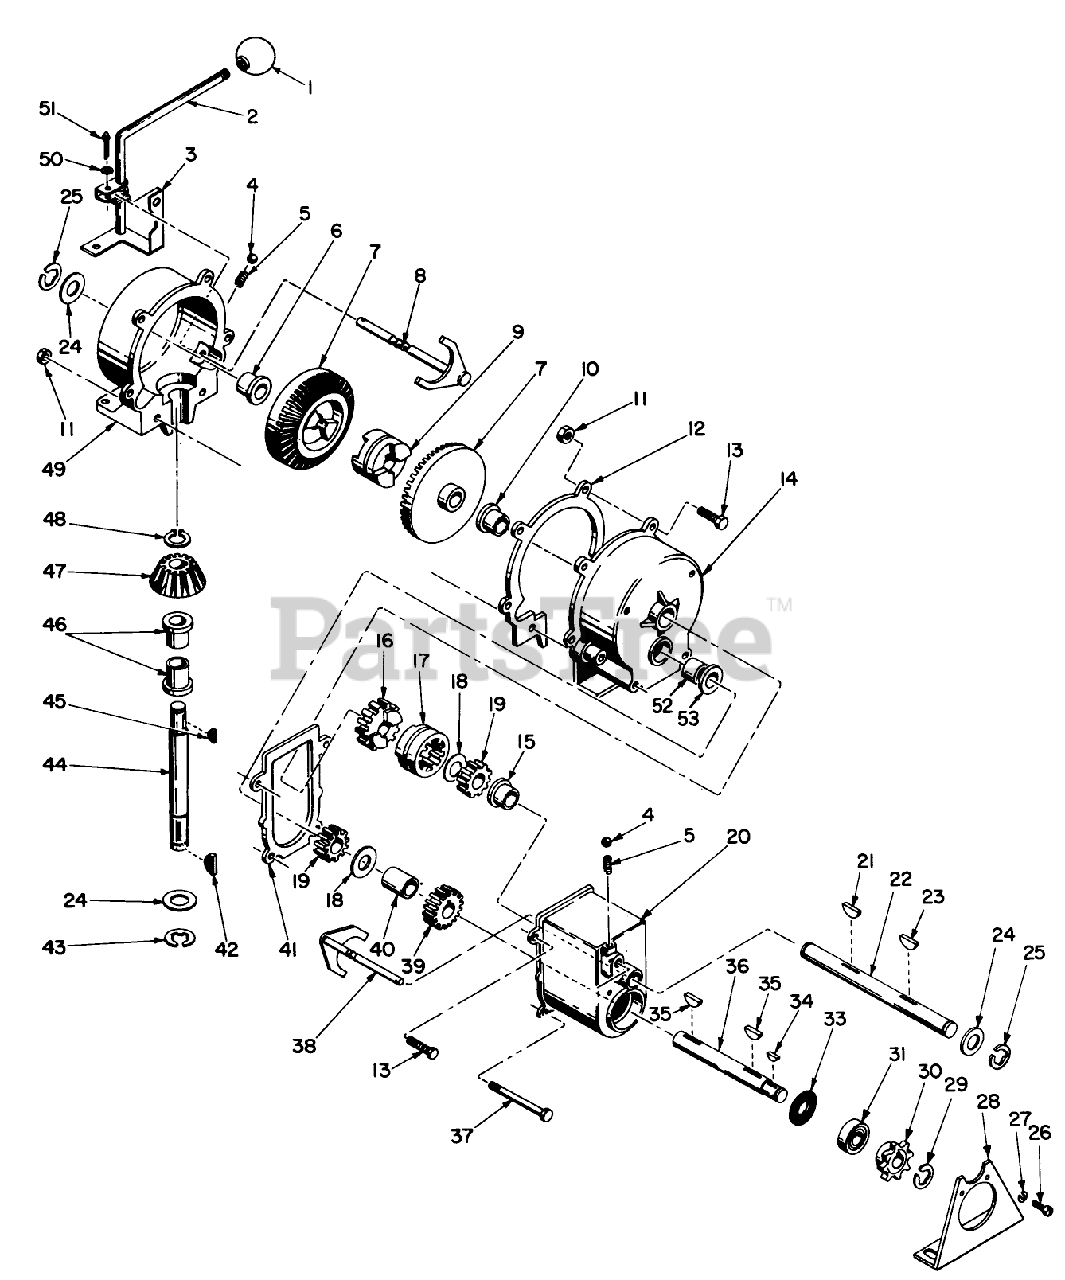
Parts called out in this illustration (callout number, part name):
2	Shifter Lever Assy
3	Bracket, Shift Lever
5	Spring, Detent
6	Bearing, Flange
8	Detent Shaft Assy
9	Clutch Collar
10	Bearing, Flange, 1-1/4 in. flange
11	NUT-HEX
12	Gasket (0.006)
13	SCREW-HH
15	Bearing, Flange, 1 in. flange
16	Gear (17T-Int. shaft)
17	Clutch Collar
19	Gear (13T)
20	Housing, 2 speed
21	KEY-WOODRUFF
22	Shaft, Internal
23	Key, HI-Pro No. 606 (0.875)
26	10-24 X 1/2 FIL HD MS
27	WASHER-LOCK
28	Bracket, Outboard
29	Snap Ring (1000-50)
31	Bearing, Ball
33	Shim, 0.010 in. thick
35	KEY-WOODRUFF
36	Shaft, Output
37	SCREW-HH
38	Detent Shaft Assy
39	Gear (17T-Output Shaft)
40	Spacer
41	Gasket (0.020)
42	KEY-WOODRUFF
44	Shaft, Input
45	Woodruff Key
46	Bearing, Flanged, Keyed
47	Pinion, Bevel
48	Snap Ring
49	Housing Half, with detent hole
50	Lockwasher
51	PIN-COTTER
52	Needle Bearing
53	Thrust Washer
